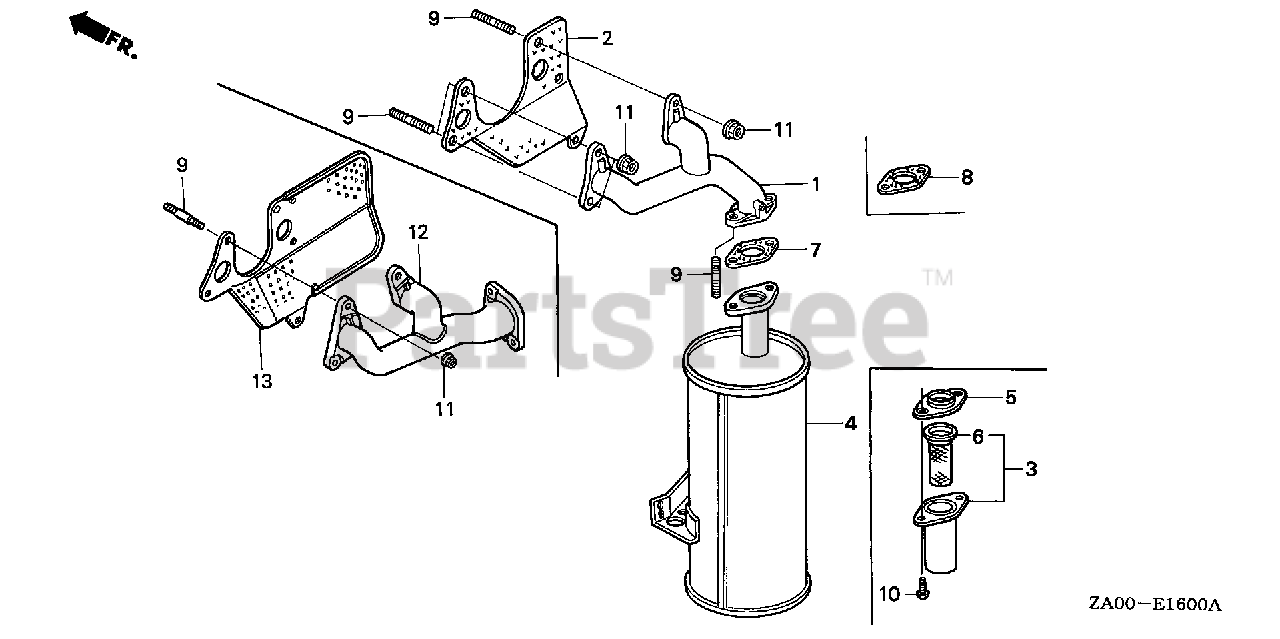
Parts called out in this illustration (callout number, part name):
1	MANIFOLD, EX.
2	GASKET, EX.
3	CAP SET, ARRESTER (NOT AVAILABLE)
5	BASE, ARRESTER
6	ARRESTER, SPARK
7	GASKET, MUFFLER
8	GASKET, MUFFLER
9	BOLT, STUD (8X35)
10	SCREW, PAN (5X8)
11	NUT, FLANGE (8MM)
